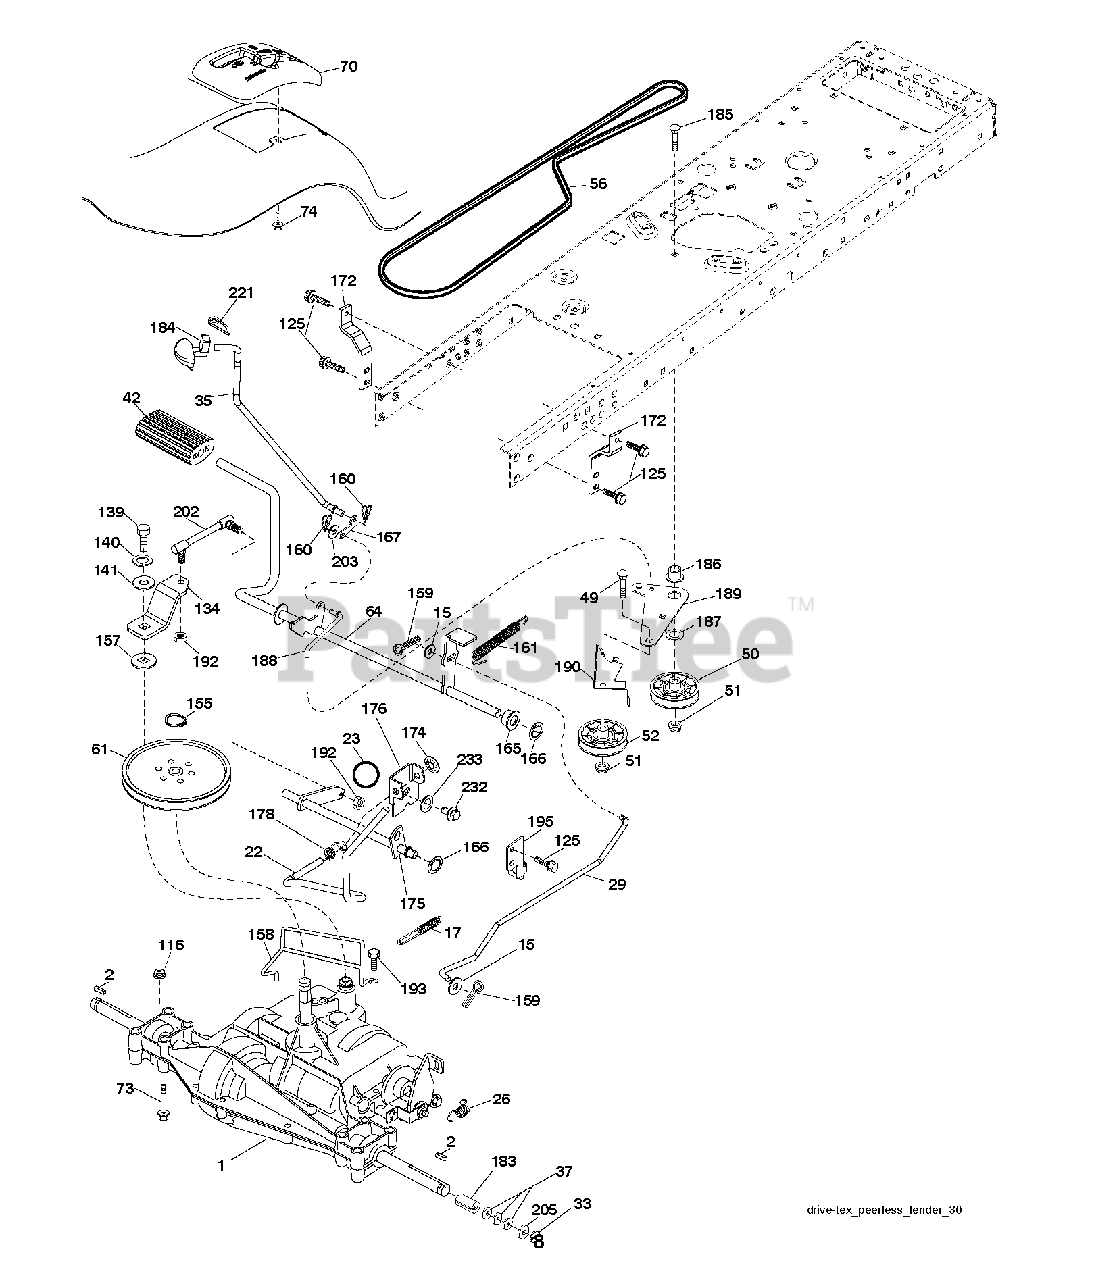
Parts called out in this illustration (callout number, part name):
2	SQUARE KEY
17	SPRING.BRAKE.PEERLESS.TEX
22	ROD.SHIFT.FENDER.TLT.2006
23	KNOB.DUCKHEAD.1/2
26	SPRING.BRAKE.RTN.GR.DR
29	ROD.BRAKE.PEERLESS
33	E-RING LT
35	ROD, BRAKE, PARK
42	PEDAL COVER T
49	BOLT
50	IDLER.FLAT.910.OFFSET
51	NUT LOCK FLG 3/8-16 UNC
52	IDLER.V-GROOVE.910.OFFSET
56	V-BELT.TRACTOR.DRIVE.P
61	PULLEY TRANS
64	SHAFT.ASM.PEDAL.BRAKE.
70	CONSOLE.SHIFT.
73	BOLT HEX 5/16-18 GR 5
74	SCREW.HI-LO.CONSOLE
116	NUT LOCK HEX FLANGE 5/16-18
125	SCREW
134	ARM SHIFT
139	BOLT 1/4-28X3/4
140	LOCKWASHER
141	WASHER LT
155	RETAINING RING LT
157	WASH-SHFT PLT LT
158	KEEPER.PMS.18/20.D4365
159	COTTER PIN
160	RETAINER CLIP
161	SPRING, RETURN LT
165	BUSHING.SHAFT.BRAKE.HAND
166	NUT.PUSH.625.2006
167	LATCH.BRAKE.SPRING
172	STRAP.TRQ.LH.GEAR.DRIV
174	NUT.PUSH.500.2006
175	SHAFT ASM SHIFT
176	ARM.CLEVIS.ROD.SHIFT
178	SPRING.SHIFT.GT2006
183	SPACER AXLE
184	HANDLE PARKING BRAKE
186	SPACER.RETAINER
187	WASHER 12/32X2X10GA
188	LINK.CLUTCH.GROUND.DRIVE
189	BELLCRANK.GROUND.DRIVE.TEX.
190	KEEPER.BELLCRANK.DRIVE
192	NUT LOCK CENTER 1/4 -28 FNTHD
193	SCREW 5/16"
195	BRKT.ROD.BRAKE.PEERLES
202	LINK.SHIFT.PMST.18"
203	WASHER
221	RETAINER.SPRING.CLIP.H
232	BOLT FIN HEX 7/16-14 X 1
233	WASHER SERRATED
